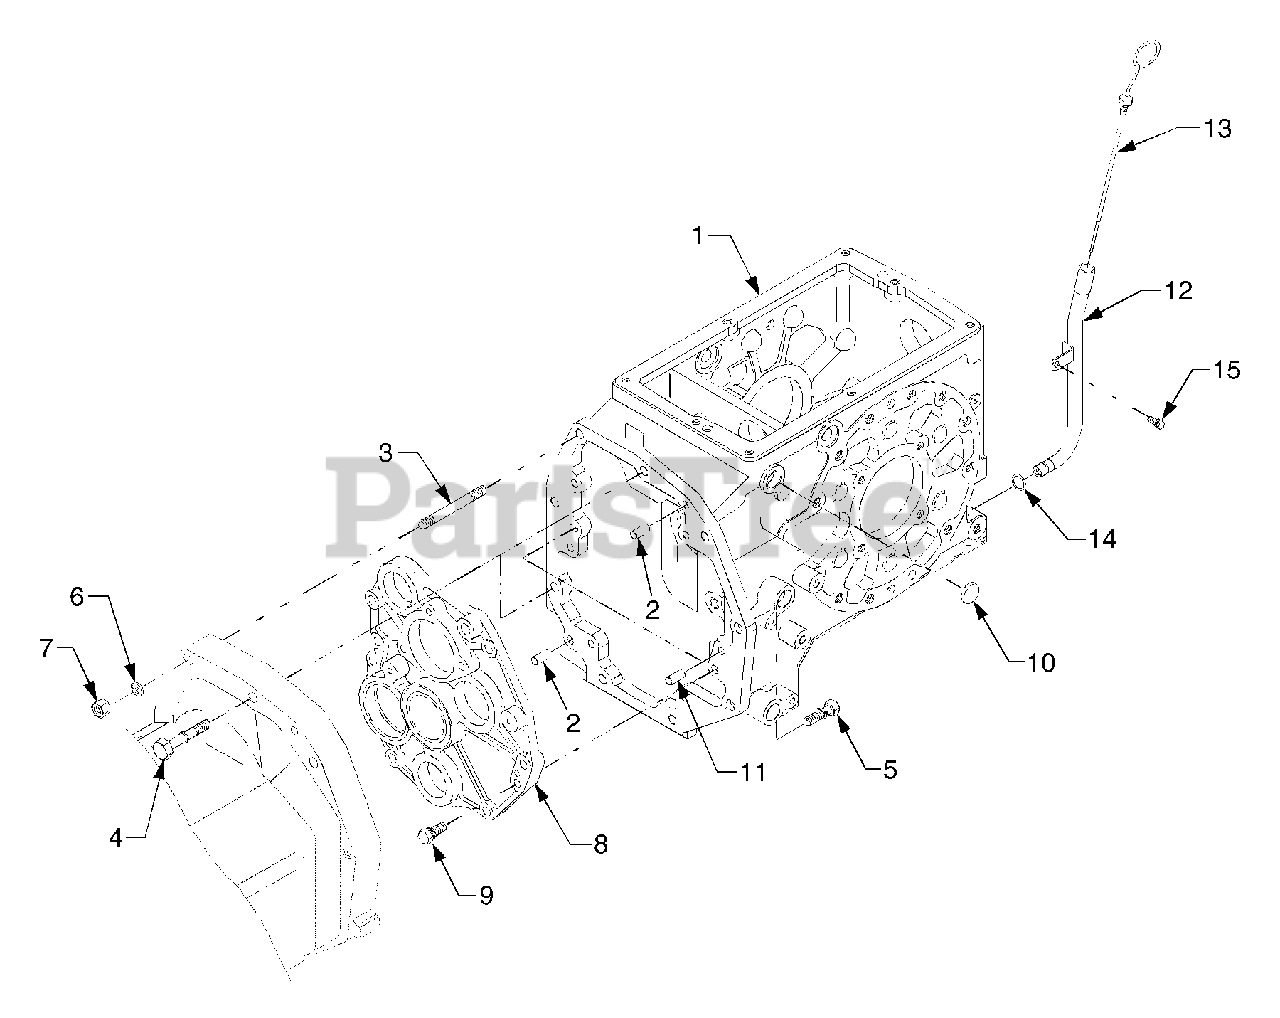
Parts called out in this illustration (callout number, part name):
1	Case, Transmission
2	Pin, Straight
6	Washer, Spring
8	Cover, Bearing
10	Plug, Expantion
11	Pin, Straight
12	Guide, Oil Gauge
13	Gauge, Oil
